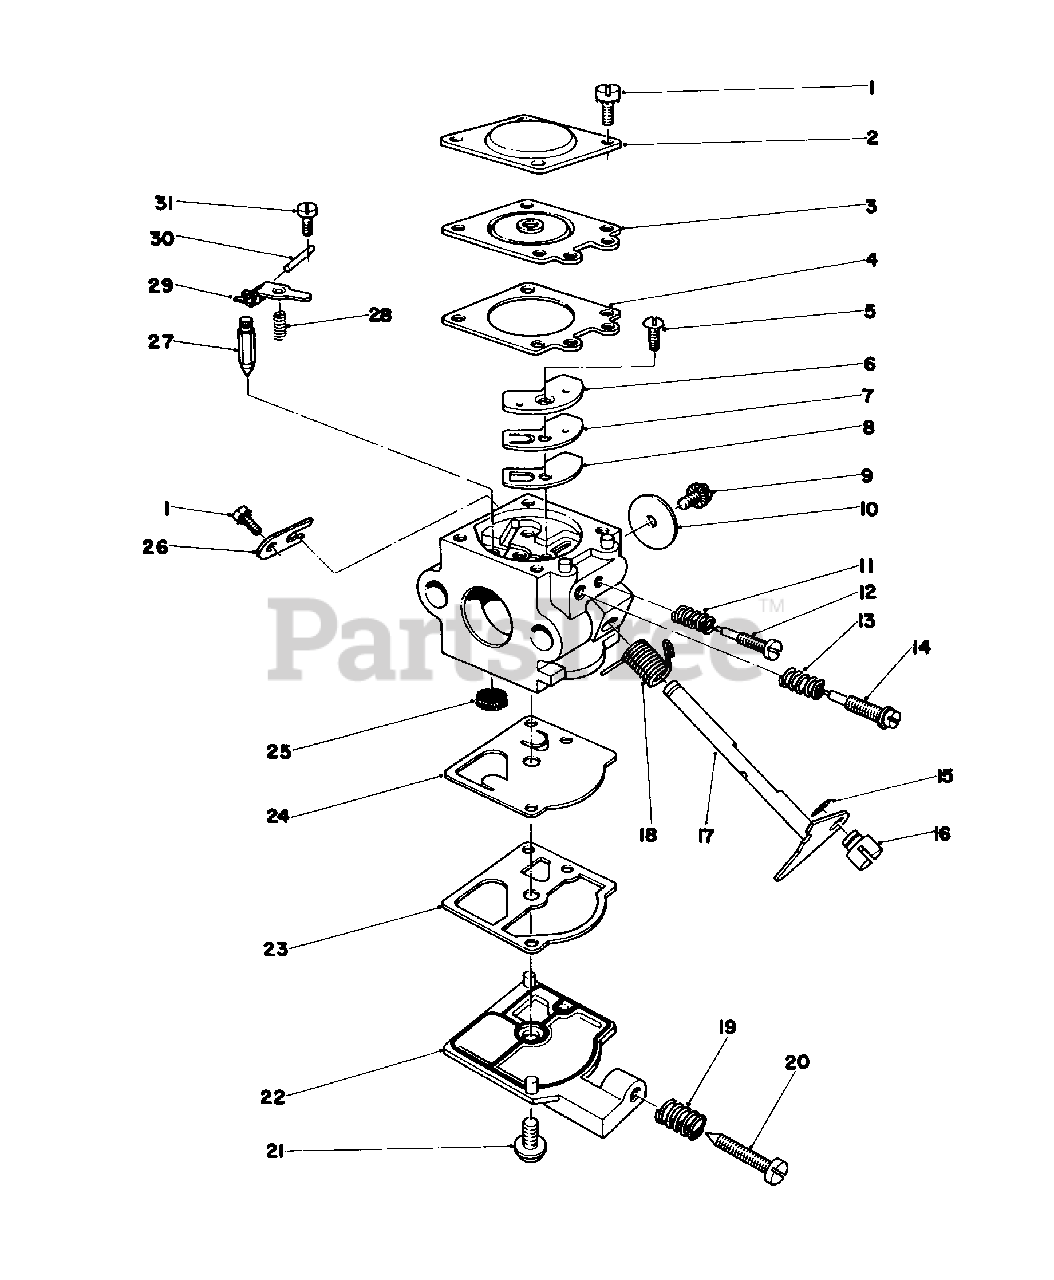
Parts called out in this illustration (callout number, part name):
2	Cover, Diaphragm
3	Diaphragm, Metering
4	Gasket, Diaphragm
5	Screw, Circuit Plate
6	Plate, Circuit
7	Diaphragm, Circuit Plate
8	Gasket, Circuit Plate
9	Screw, Throttle
10	Valve, Throttle
11	Spring, Needle-Idle
12	Idle Needle
13	Spring High Speed Needle
14	High Speed Needle
17	Throttle Shaft
18	Spring, Throttle Return
19	Spring, Idle Adjust Screw
20	Screw, Idle Adjust
21	Screw, Fuel Pump
22	Cover, Fuel Pump
23	Gasket, Fuel Pump
24	Diaphragm, Fuel Pump
25	Screen, Inlet
26	Clip, Throttle Shaft
27	Valve, Inlet Needle
28	Spring, Metering Lever
29	Lever Metering
30	Pin, Metering Lever
31	Screw Metering Lever Pin
